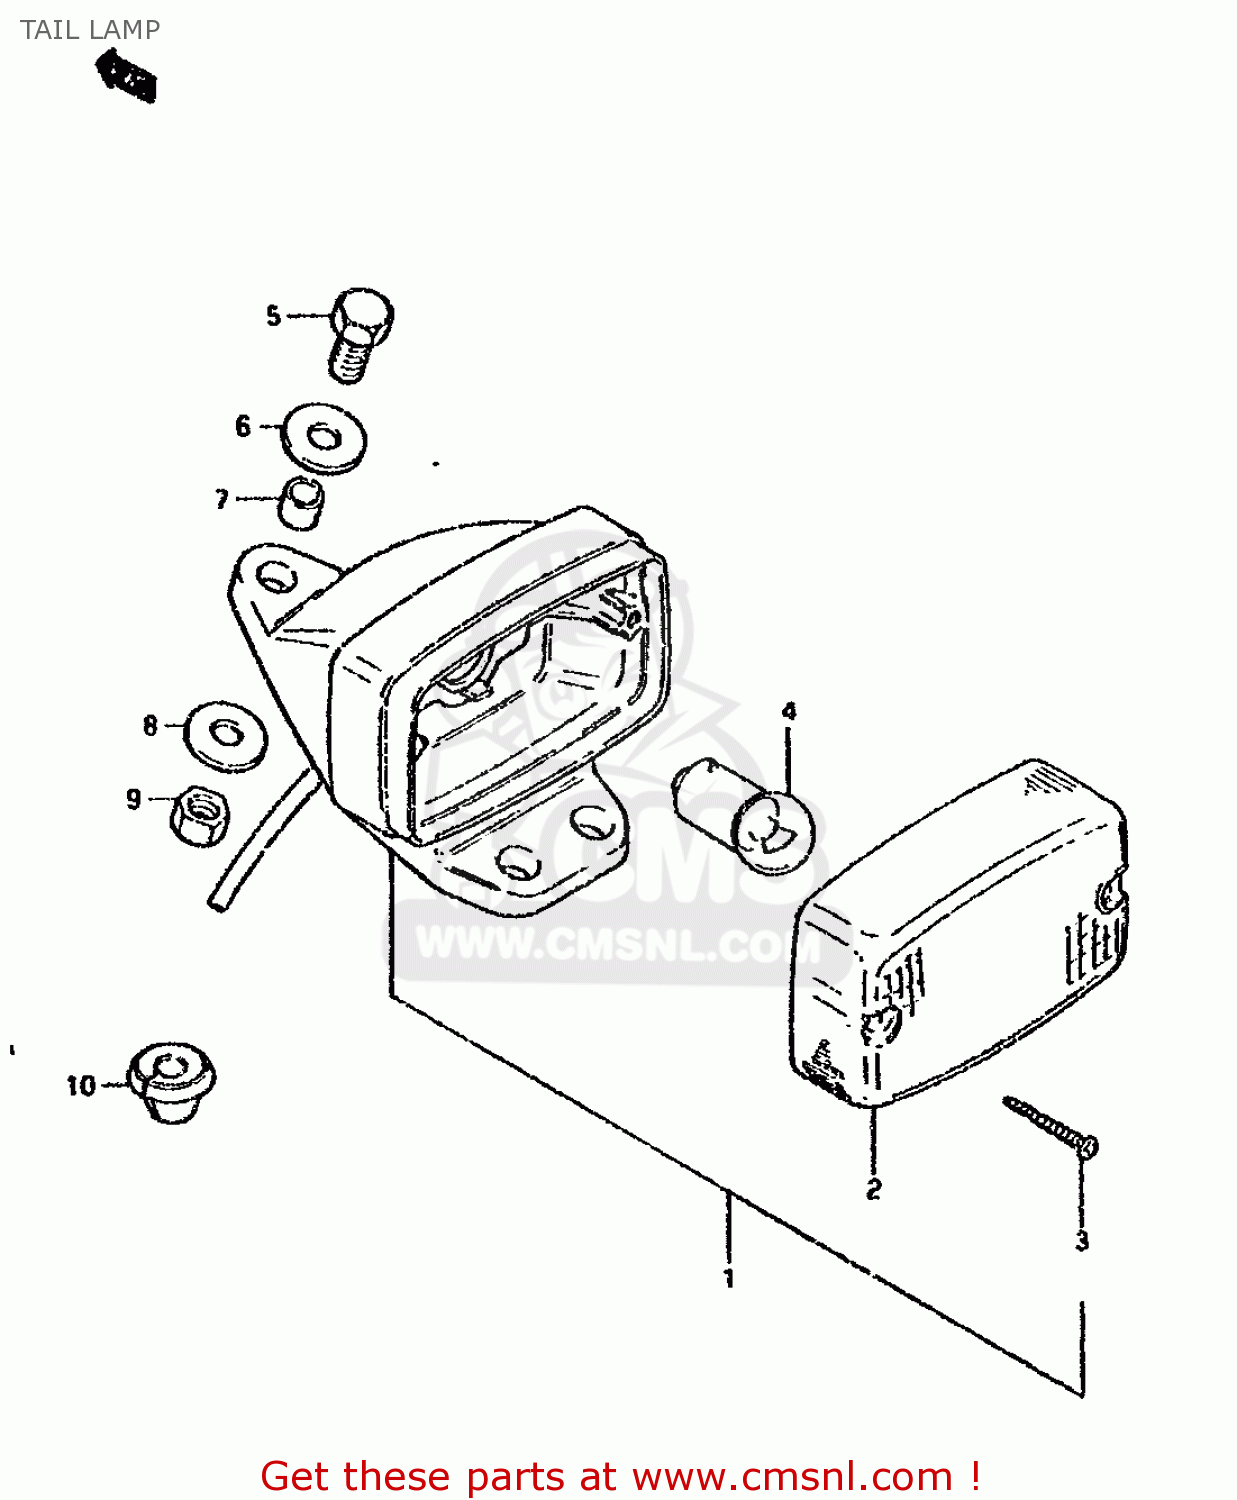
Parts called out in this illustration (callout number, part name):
1	LAMP ASSY,TAIL
2	LENS
3	SCREW
4	BULB(6V5W,TOKAI DENSO)
5	BOLT
6	WASHER
7	SPACER (6.1X9X9)
8	WASHER
9	NUT 6MM
10	GROMMET
